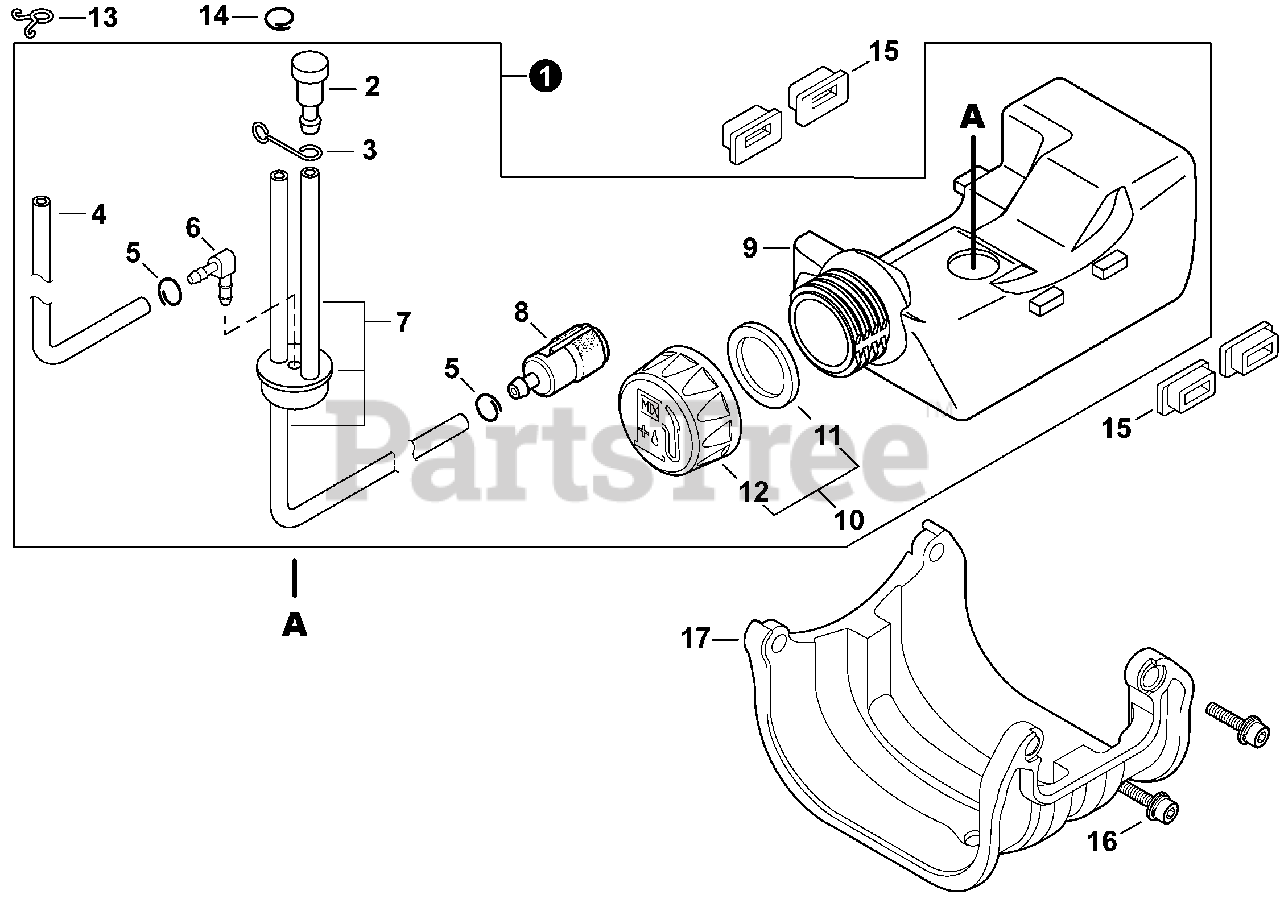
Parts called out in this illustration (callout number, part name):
1	TANK ASSY, FUEL
2	VENT ASSY
3	CLIP, VENT ASSY
4	PIPE, FUEL RETURN
5	CLIP Ø6
6	CONNECTOR, PIPE
7	PIPE, FUEL
8	FILTER, FUEL 125-528
9	TANK, FUEL
10	CAP ASSY, FUEL
11	GASKET, FUEL CAP
12	CAP, FUEL
13	CLIP, SPRING Ø5.2
14	CLIP Ø6
15	CUSHION, FUEL TANK
16	BOLT M5×16
17	GUARD, PLASTIC FUEL TANK
